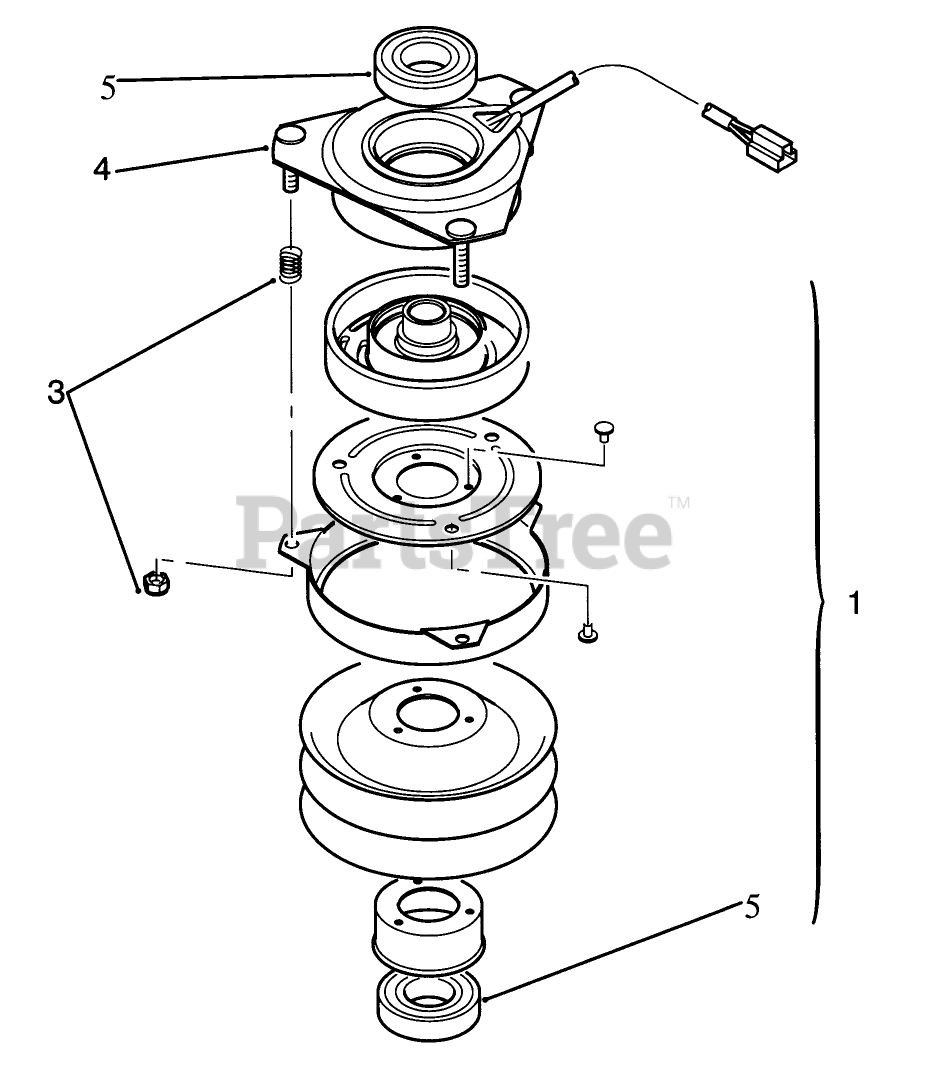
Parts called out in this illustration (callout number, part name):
1	Rotor, Armature Ass-y (Incl. Ref. #5)
3	ACCESSORY PKG SRVC PART
4	Assembly-Field (Incl. Ref. #5)
5	BEARING-ELEC CLUTCH
